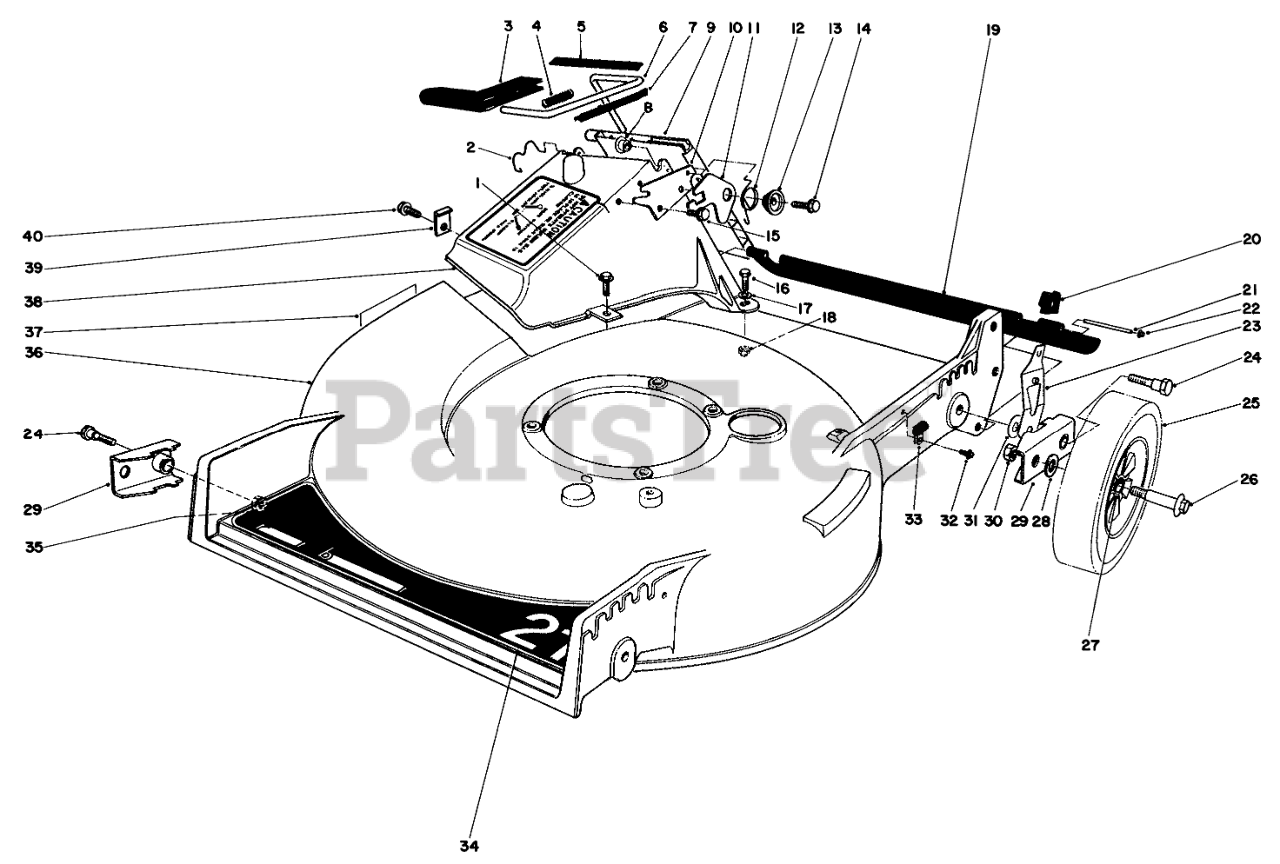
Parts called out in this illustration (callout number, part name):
1	Screw
2	DOOR RET SPRING
3	Handle-Door
4	Spring
5	DOOR COVER
6	DOOR ROD +
7	DOOR HANDLE COVER
8	BUSHING-NYLON
9	Door Discharge
10	DOOR LATCH PLATE
11	SAFETY LATCH
12	TORSION SPRING
13	DOOR SPACER
14	SCREW-HWH
15	SCREW-PLASTITE
16	SCREW-HH
17	WASHER-FLAT
18	NUT-LOCK, NI
19	SHIELD - TRAILING
20	KNOB-ARM
21	SHIELD ROD
22	Push Nut
23	Spring Arm
24	PIVOT SCREW
25	Wheel 8 Tire Assembly (Incl. Ref. #27)
26	BOLT-WHEEL
27	BUSHING
28	WASHER
29	HP PIVOT ARM ASM
30	Nut
31	WASHER-PIVOT
32	SCREW
33	CLAMP-CABLE
34	DECK DECAL
35	NUT-LOCK, NI
36	Housing (Incl. Ref. #37)
37	DECAL-DANGER
38	Tunnel Discharge
39	TUNNEL CLIP
40	SCREW
